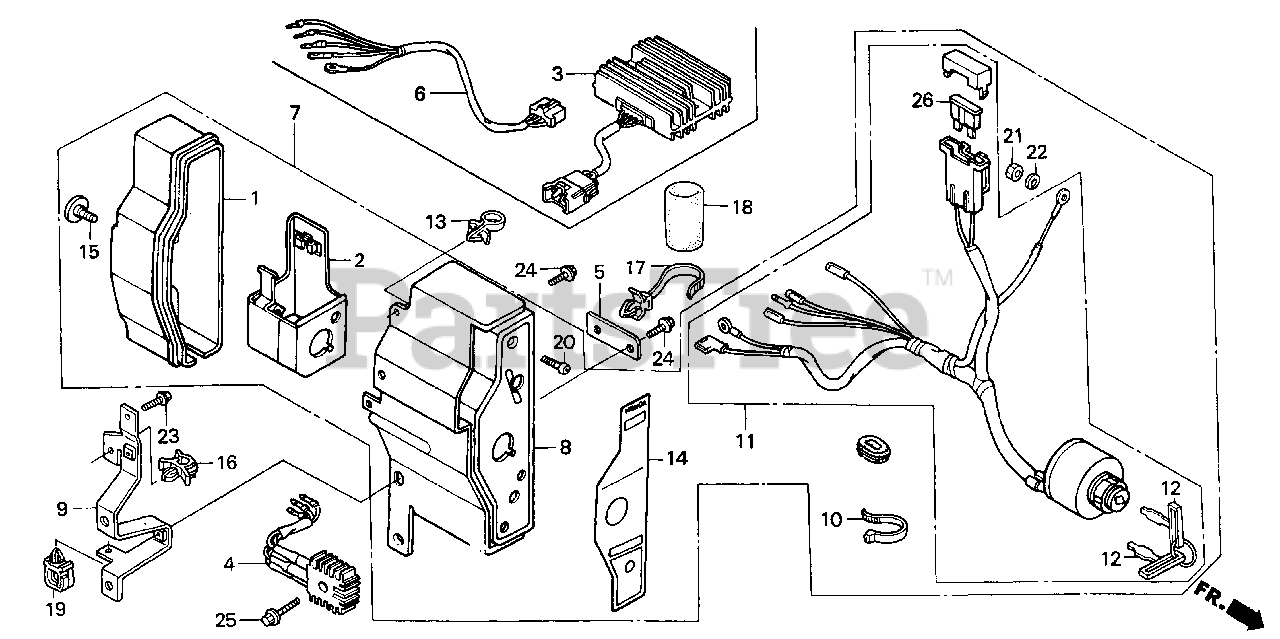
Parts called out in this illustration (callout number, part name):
1	CASE, CONTROL
2	BRACKET, CASE MOUNTING
3	RECTIFIER ASSY., REGULATOR (20A)
5	BRACKET, WIRE HARNESS CLIP
6	SUB-WIRE HARNESS ASSY.
7	BOX ASSY., CONTROL
8	PANEL COMP., CONTROL
9	STAY, CONTROL BOX
10	BAND
11	SWITCH ASSY., COMBINATION
12	KEY COMP.
13	HOLDER, STOP SWITCH WIRE
14	MARK, CONTROL BOX (EXTERNAL-REGULATOR)
15	SCREW, SPECIAL (6X12)
16	CLIP, WIRE HARNESS
17	BAND, WIRE HARNESS (150MM) (BLUE)
18	TUBE, CORD (30MM)
19	CLIP, WIRE HARNESS
20	SCREW, PAN (4X12)
21	NUT, HEX. (4MM)
22	WASHER, SPRING (4MM)
23	BOLT, FLANGE (6X10)
24	BOLT, FLANGE (6X12)
26	FUSE, BLADE (25A)
